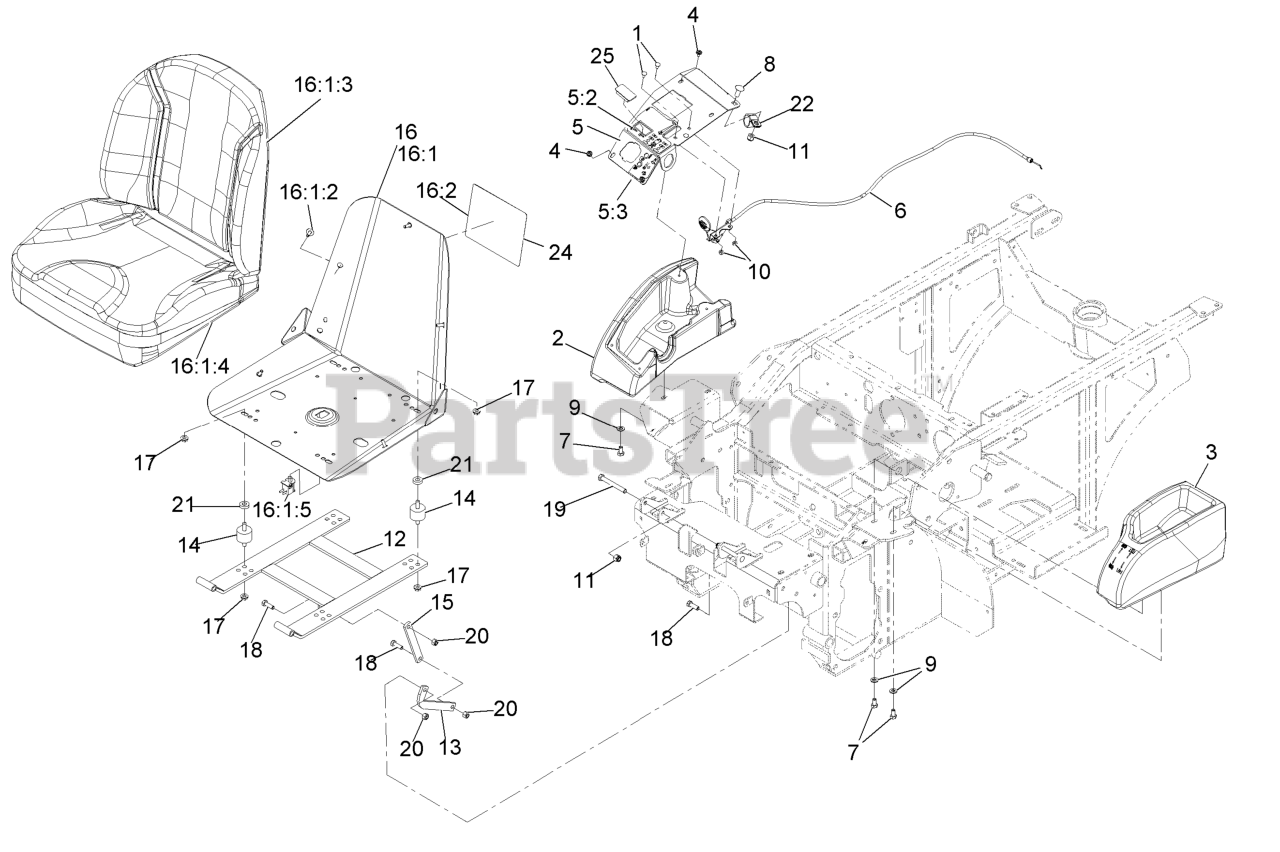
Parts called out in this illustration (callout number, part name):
1	Bolt-Carriage #10-24 X 1/2
2	Console-RH
3	Console, LH Grey
4	Screw-PPH #10-24 X 1/2
5	Control Panel ASM
5:2	Decal-Console
5:3	Decal-Speed Control
6	Cable-Throttle
7	Screw-HH 5/16-18 X 5/8
8	Bolt-Carriage 3/8-16 X 7/8
9	Washer-5/16 SAE
10	Nut-Nyloc #10-24
11	Nut-Nyloc 3/8-16
12	Frame-Seat
13	Link-Seat Stop
14	Mount-Vibration, Rubber
15	Link-Seat
16	ASM-Seat W/Decal
16:1	ASM-Seat, Navigator
16:1:2	Bolt-Seat
16:1:3	Cushion-Seat, Back
16:1:4	Cover-Seat Bottom Svc
16:1:5	Switch-Bail
16:2	Decal-Service Aid
17	Nut-Whizlock 5/16-18
18	Screw-HH 5/16-18 X 1
19	Screw-HH 3/8-16 X 3
20	Nut-Nyloc 5/16-18
21	Spacer
22	Clip-Loom
24	Decal-Service Aid
25	Plug-Hole
